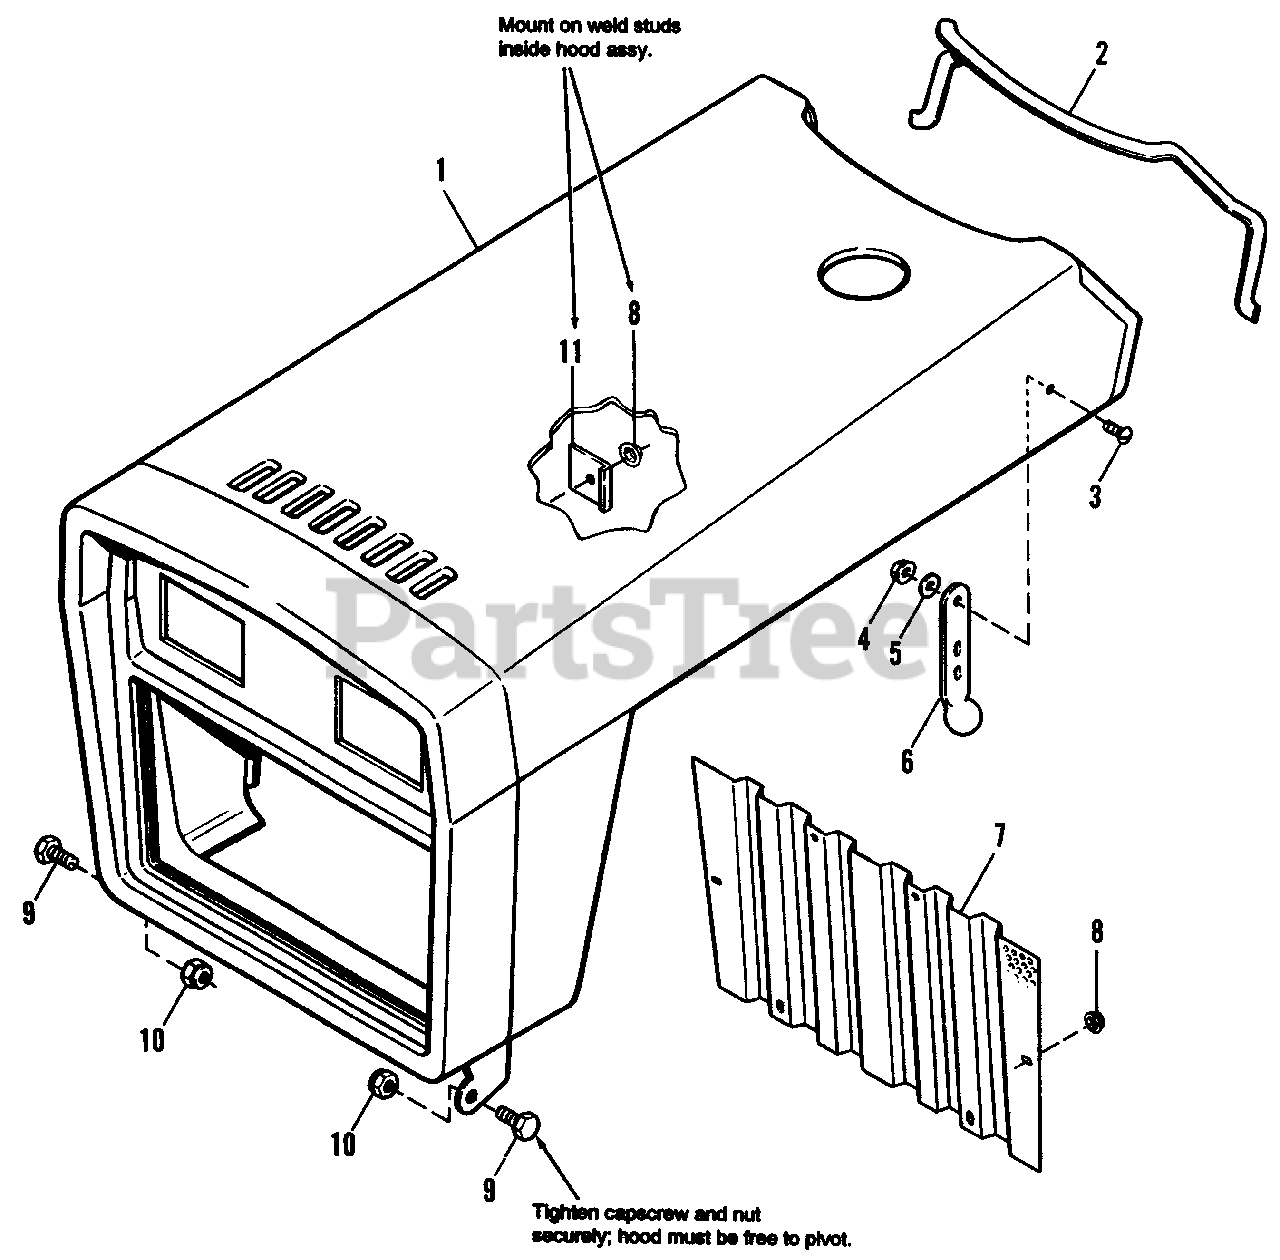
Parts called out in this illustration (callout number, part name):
1	HOOD & GRILLE ASSY.
2	MOULDING, Hood
3	SCREW, Truss Hd., #10-32 x 1/2
4	LOCKNUT, Hex, #10-32
5	WASHER, Special
6	STRAP, Hood
8	LOCKNUT, Pal
9	CAPSCREW, Hex Hd., 3/8-16 x 1
10	LOCKNUT, Hex, 3/8-16
11	CLIP, Headlight Mounting
